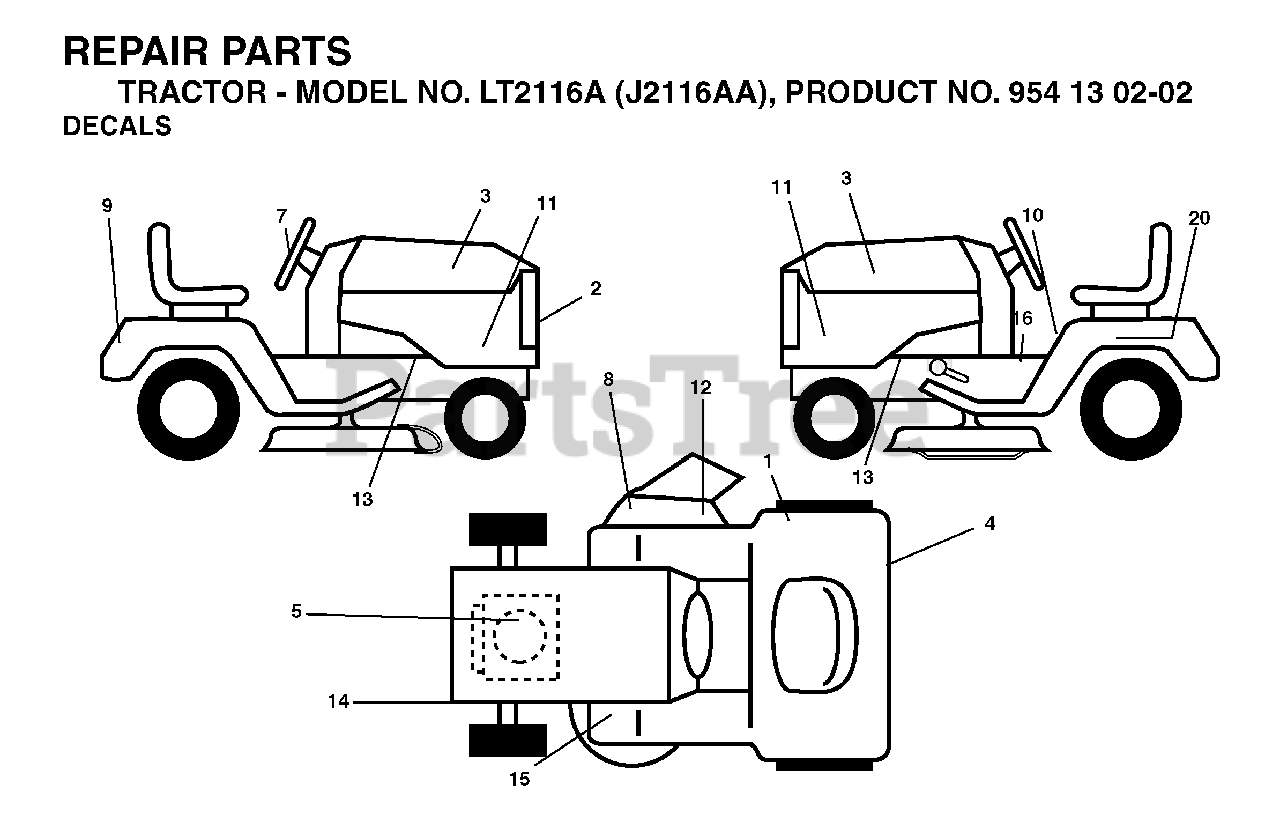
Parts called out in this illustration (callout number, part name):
8	DECAL.INTERNATIONL.CUTFINGER
10	DECAL READ OWNER'S MAN SYMS
12	DECAL DECK "B" 42"
14	DECAL V BELT SCHEMATIC
16	DECAL PARK BRAKE
20	DECAL BTRY SYMBOLS
